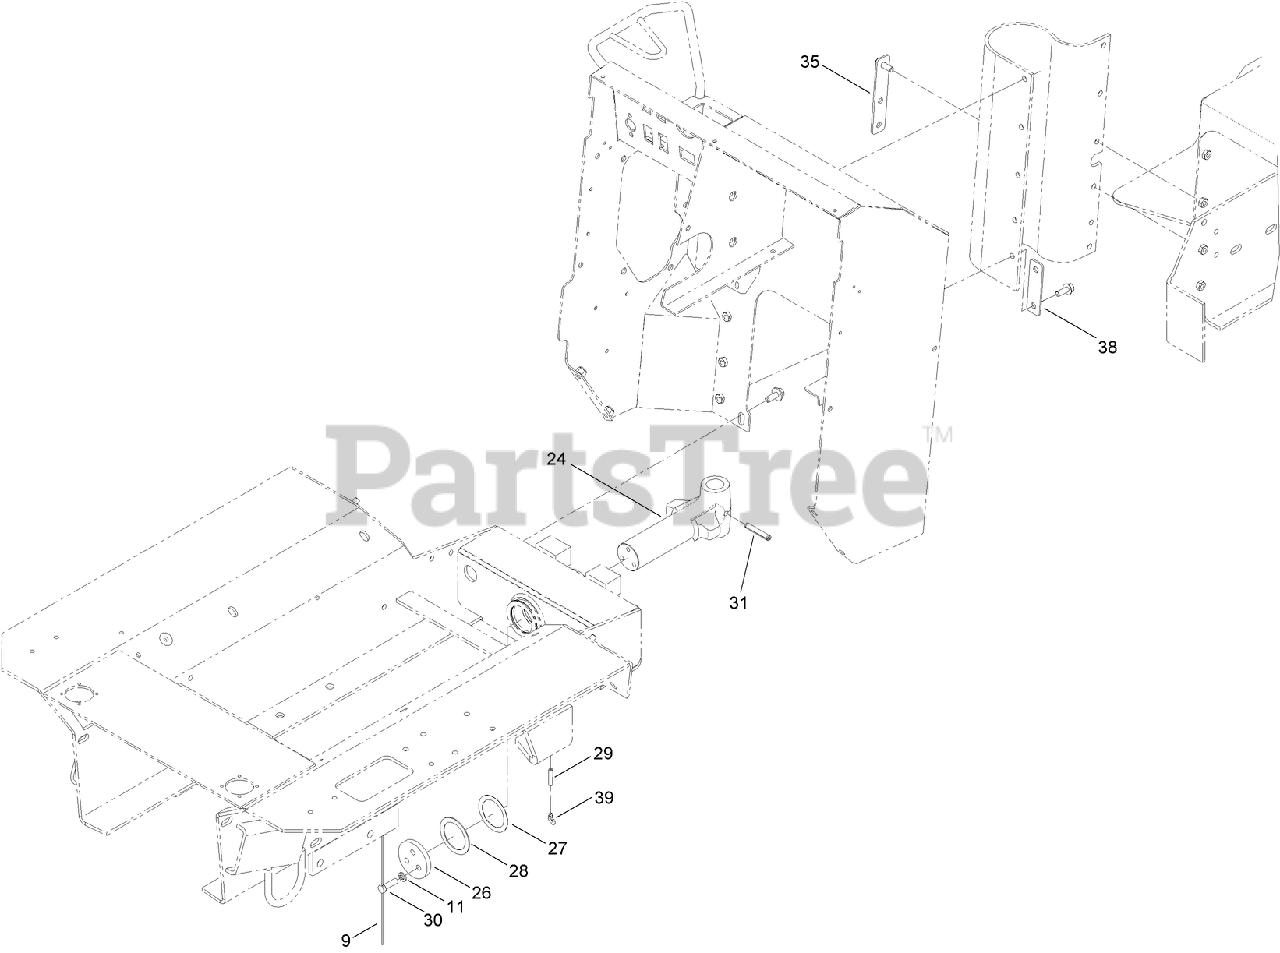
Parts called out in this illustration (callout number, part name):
9	WIRE-STEEL
11	WASHER-LOCK
24	PIVOT-ARTICULATION
27	SHIM-THIN
29	FITTING-LUBE
30	SCREW-HH
31	PIN-SLOTTED, SPRING
39	FITTING-GREASE
